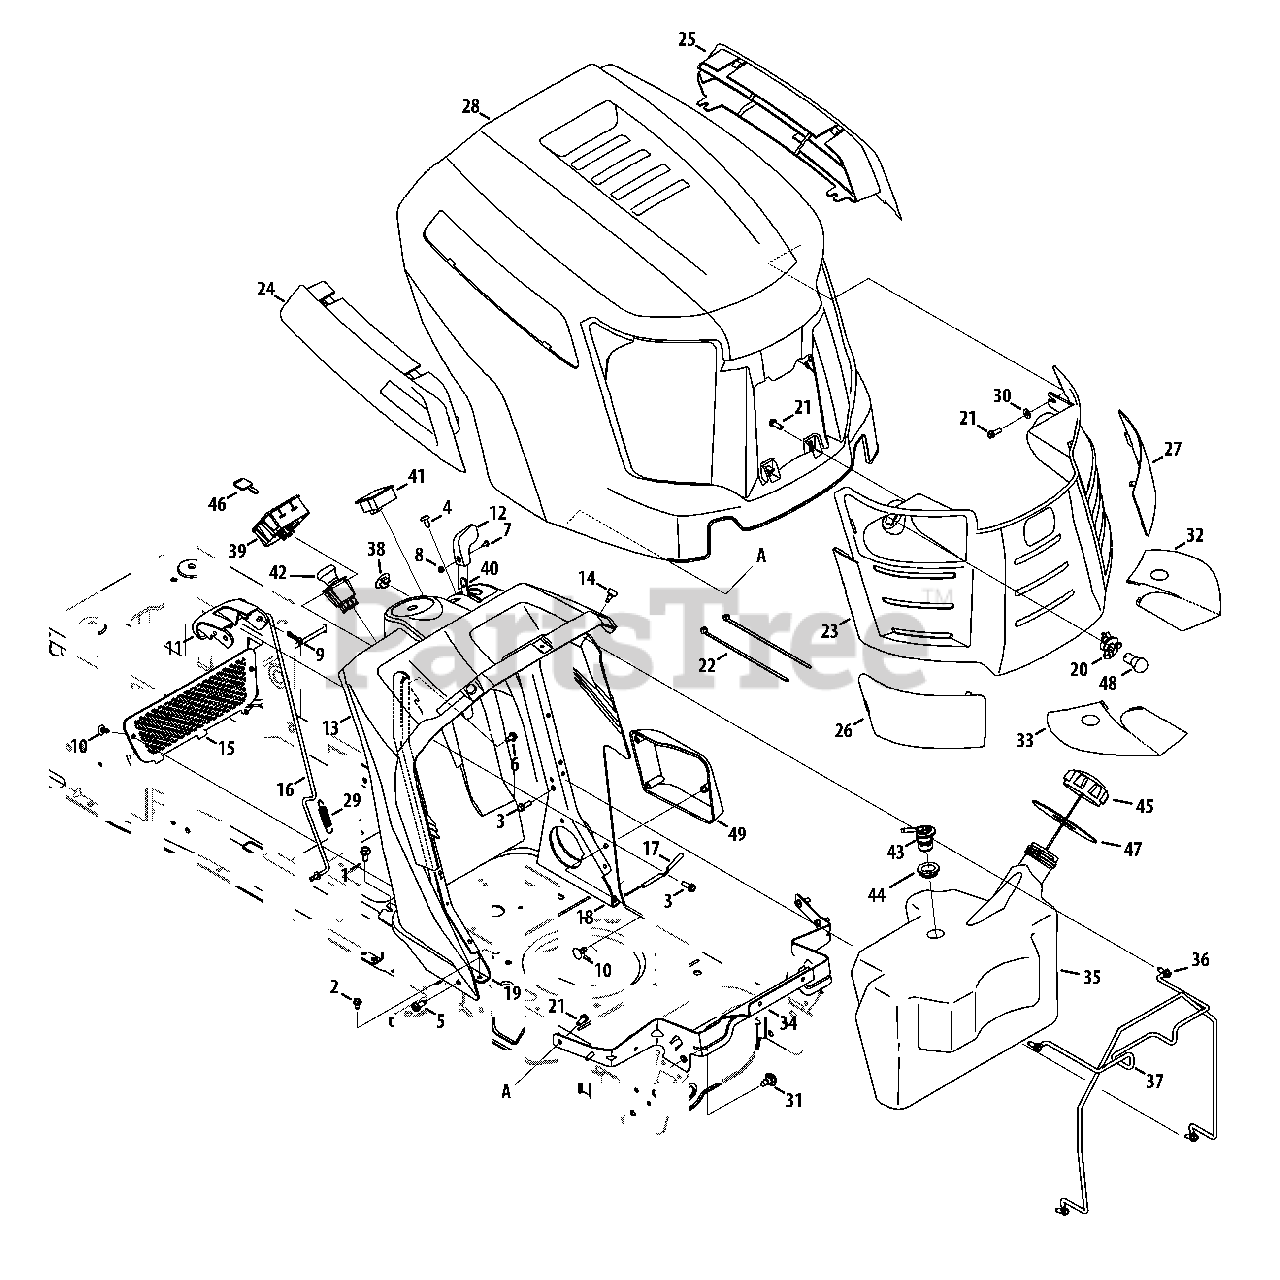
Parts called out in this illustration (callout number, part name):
1	Screw, Self-tapping, 5/16-18, .750
2	Screw, Self-tapping, 1/4-20, 0.500
3	Screw, HL, 1/4-15, 0.750
4	Screw, Ab, 1/4-14, 0.625,
5	Screw, Self-tapping, 5/16-18, 0.750,
6	Screw, Self-tapping, 1/4-20 x .625
7	Screw, Mach, #8-32, 0.375
8	Nut, Hex, #8-32
9	Pin, Cotter, Bow-Tie 72
10	Clip, Ratchet, .250 Dia
11	Lever, Dash, Cruise/Brake
12	Knob, Throttle
13	Dash Panel, A-Style
14	Bumper, .62 Dia X .3
15	Net
16	Rod, Control, Latch Cub
17	Rod, Lever, Bent
18	Support, Dash, Plate LH
19	Support, Dash, Plate RH
20	Socket, Lamp
21	Screw, 1/4 Dia, .750
22	Tie, Cable, Push Mount 7.5 Lg
23	Grille Ass’y (Incl. 26, 27, 32 & 33)
24	Scoop, Hood, RH A-Style
25	Scoop, Hood, LH A-Style
26	Lens, Hood, RH A-Style
27	Lens, Hood, LH A-Style
28	Hood, A-Style
29	Spring, .500 Dia. x 2.733
30	Washer, Flat, .271, .630, .065
31	Screw, Shoulder, .43x.29, 5/16-18
32	Reflector, Cub A Style, LH
33	Reflector, Cub A Style, RH
34	Bracket, Pivot, Hood A-Style
35	Tank, Fuel, 3.30 Gal.
36	Screw, Self-tapping, 1/4-20, .625
37	Rod, Support, Fuel Tank
38	Plug, Choke
39	Module Switch, Ignition
40	Cable, Throttle/Choke, 38"
41	Meter, Indicator
42	Switch, Electric PTO, Yellow
43	Valve, Rollover Grommet
44	Grommet, Rubber, 23.0 ID
45	Cap, Fuel
46	Key, Assembly
47	Gasket, Fuel Tank
48	Lamp, 12v
49	Cover, Power Steering Motor
